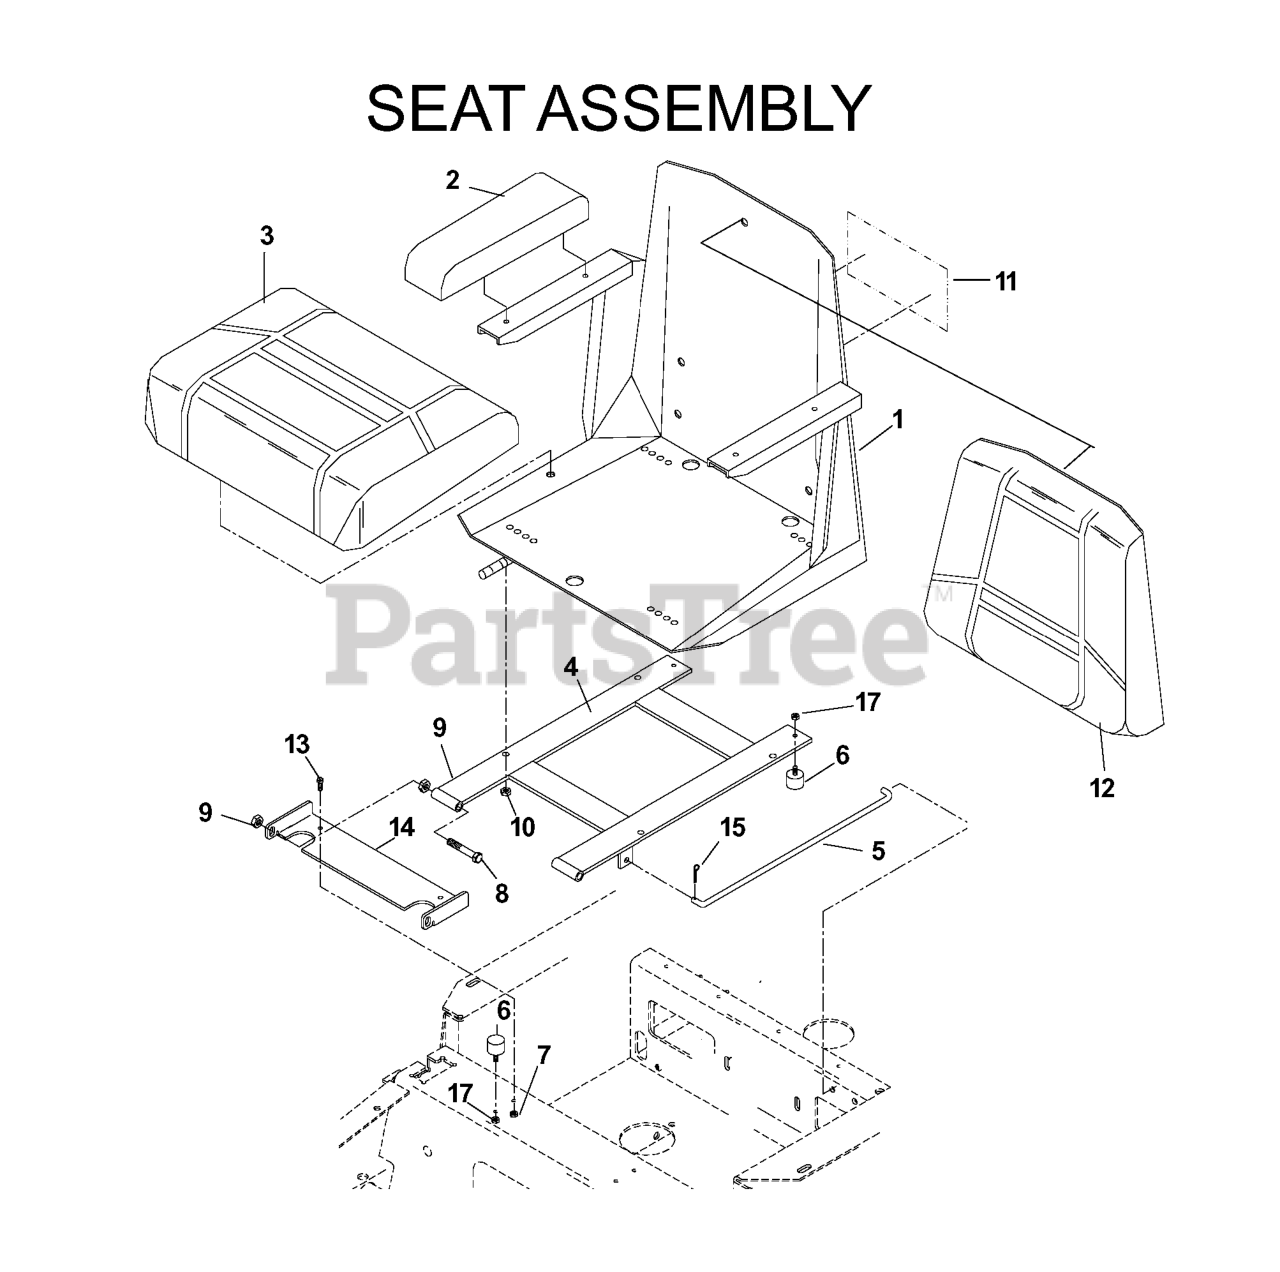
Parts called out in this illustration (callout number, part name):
1	SEAT, COMPLETE
2	ARM REST CUSHIONS/PAIR
3	SEAT CUSHION W/SWITCH
4	SEAT MOUNT
6	STUD/PLATE MOUNT
7	NUT 1/4C CENTERLOCK
8	HCS 3/8C X 3
9	NUT 3/8C CENTERBLOCK
10	NUT 5/16C CENTERLOCK
11	DECAL, CROWN H
12	SEAT, BACK CUSHION
13	HCS 1/4C X 3/4 HCS
14	SEAT BRKT W/DECAL
15	RP_COTTER PIN 1/8 X 3/4
16	SEAT RAILS
17	NUT.1/4-20.HEX.NYLOC.ZD
